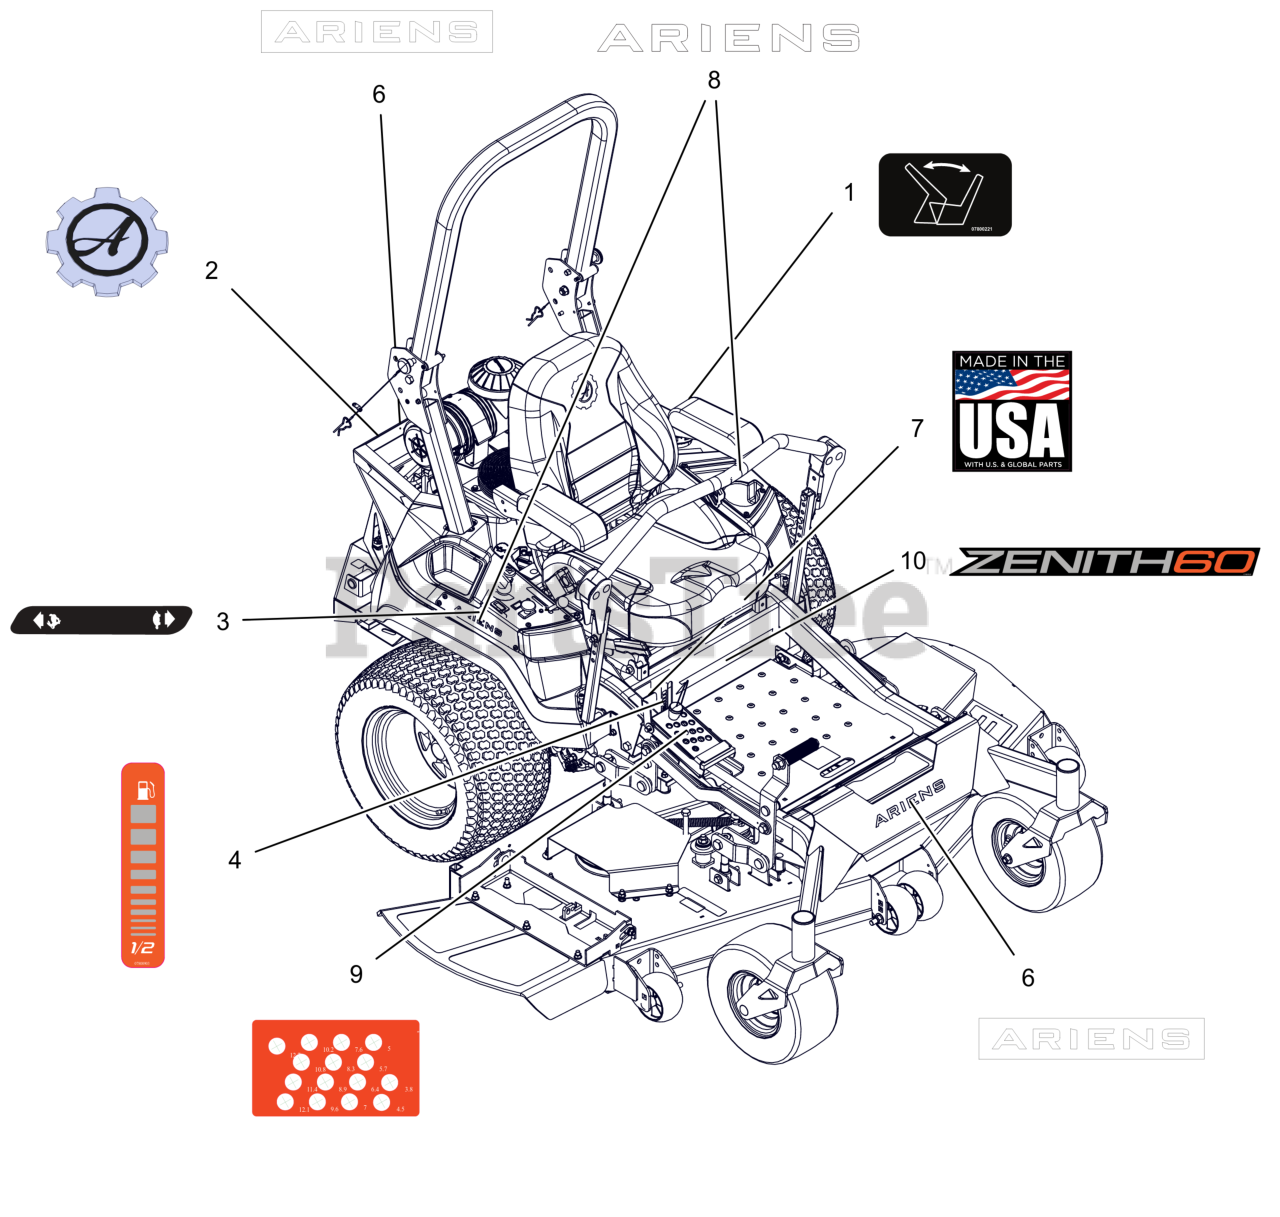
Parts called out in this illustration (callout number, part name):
1	DECAL - SEAT RELEASE
2	DECAL, ARIENS-GEAR BADGE -THK
3	DECAL, DASH DECAL
4	DECAL, ARIENS FUEL LEVEL
6	DECAL - ARIENS 9.625"
7	DECAL, MADE IN USA
8	DECAL, ARIENS (6.50")
9	DECAL, ARIENS HOC
10	DECAL, ZENITH 60
